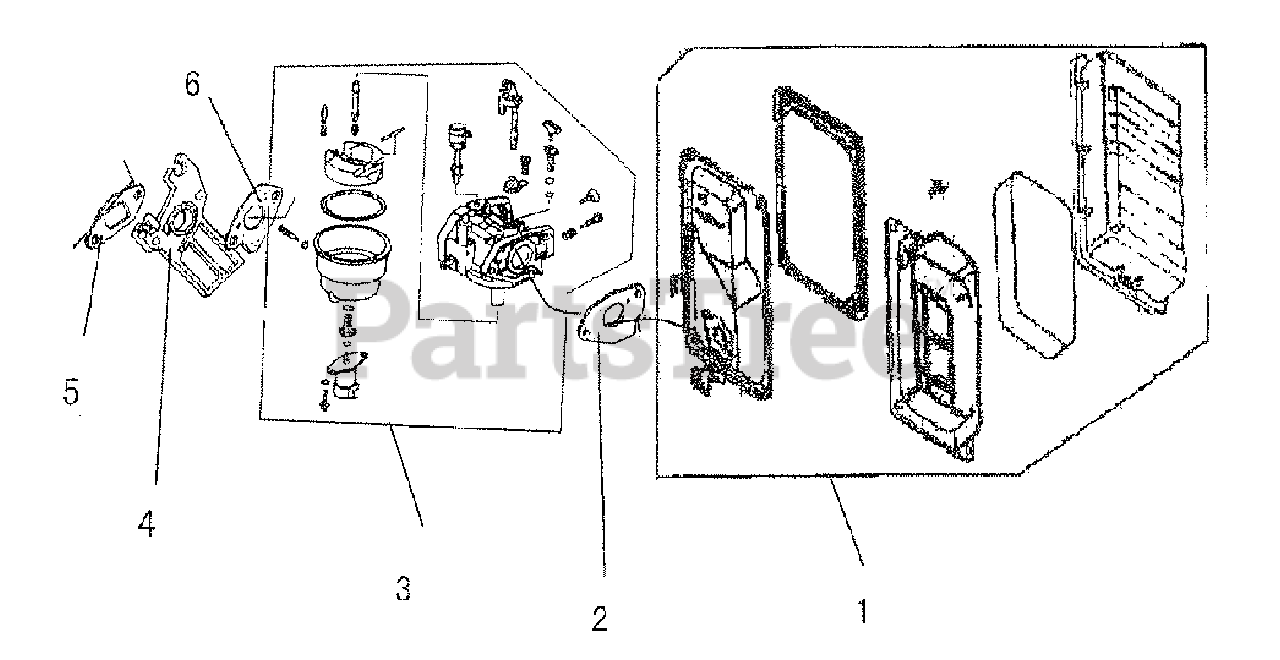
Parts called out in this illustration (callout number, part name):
2	GASKET, AIR/C
3	CARBURETOR ASSY
4	INSULATOR, CARB COMP
5	GASKET, INLET
6	GASKET, CARBURETOR
